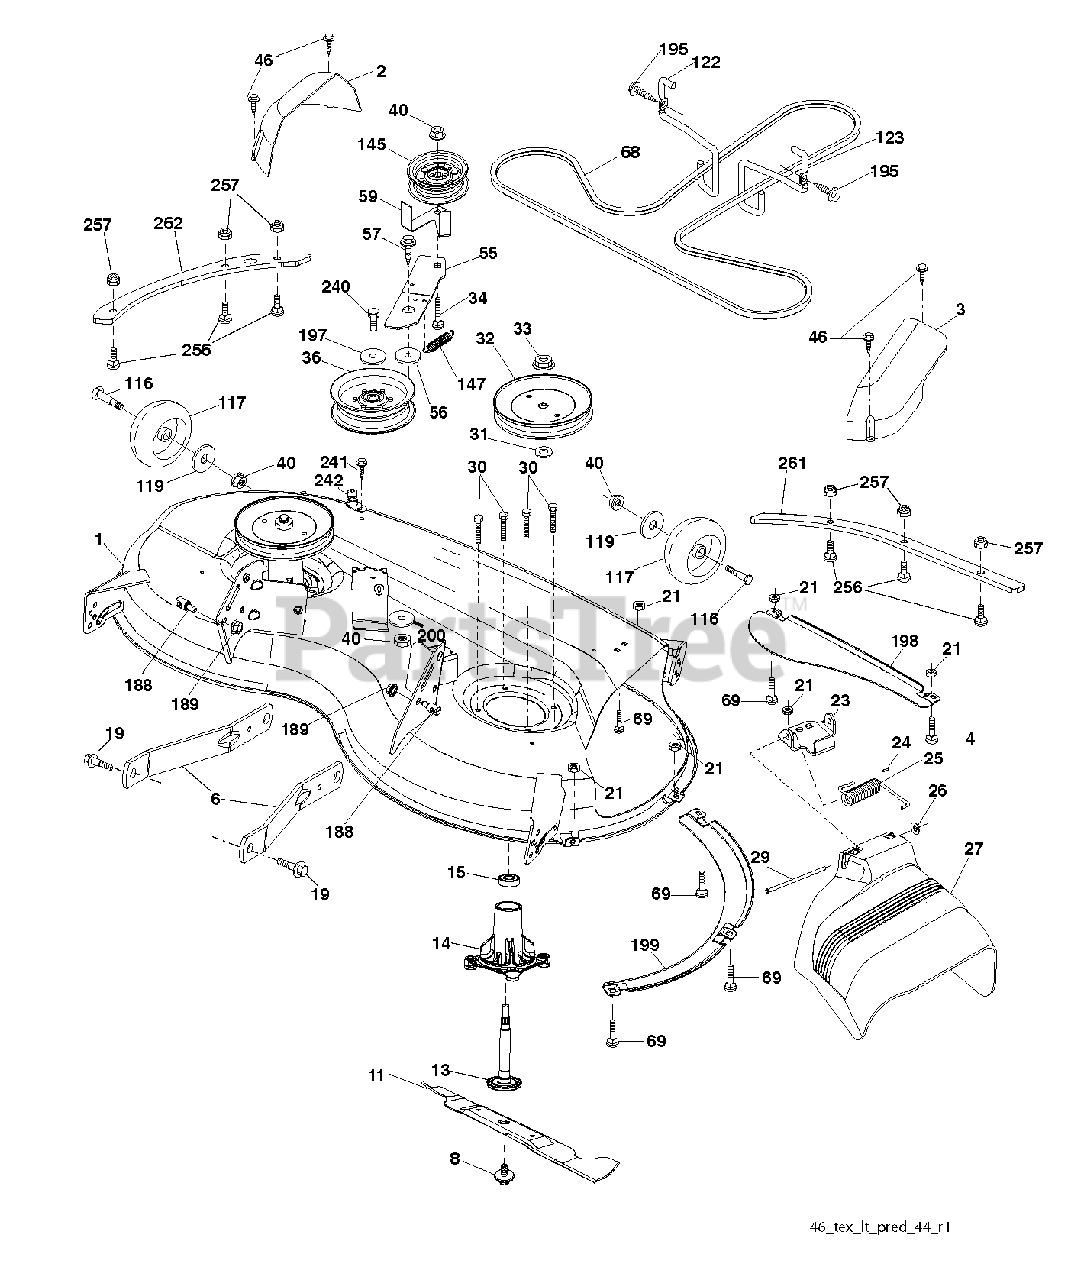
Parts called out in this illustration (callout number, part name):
1	DECK SVC 46"
2	COVER.MANDREL.RH.46"
3	COVER.MANDREL.LH.46"
4	BOLT
6	ARM.SUSPENSION.MOWER.R
8	BOLT.WASHER.ASM.7/16-2
11	BLADE.MOWER.46".HI.LIFT
13	SHAFT.ASM.MDRL.N/GREASE.38
14	HOUSING.MANDREL.4PT.
19	BOLT.SHOULDER
21	LOCKNUT
23	BRKT.DEFLECTOR.38"2005+
24	CAP-SLEEVE LT
25	SPRING.TORSION.DEFLECT
26	NUT PUSH M
27	SHIELD.DEFLECTOR.MOWER.46"BLAC
29	ROD.HINGE
30	SCREW, WASHER HEAD
31	WASHER.SPACER.MANDREL
32	PULLEY.MANDREL.5.438.PD
33	NUT.FLANGE.LOCK.TOP
34	BOLT.3/8-16X1.50
36	PULLEY.IDLER.2006
40	NUT LOCK FLG 3/8-16 UNC
46	SCREW.1/4-20X5/8
56	SPACER.RETAINER
57	SCREW 3/8-16X1
59	GUARD, BELT
68	V-BELT
69	BOLT
116	BOLT.SHOULDER.3/8-16X3-5/8.
117	WHEEL. GUAGE RALLY
119	WASHER
122	KEEPER BELT ENGINE LH
123	KEEPER BELT RH
145	PULLEY.IDLER.48"PRIMARY
147	SPRING.MOWER.DRIVE.ELECTRIC
188	STUD.FASTNER.W/ANTI-ROTATE
189	NUT LOCK HEX FLANGE 5/16-18
195	SCREW, 3/8-16X3/4
197	WASHER
198	BAFFLE CENTER FRONT
199	BAFFLE FRONT RH
200	WASHER.13/32 X 1 X 1/2.11GUARD
240	BOLT-HEX EAK
241	SCREW.TT.#10-32X.5.3/8.FLANGE
242	PORT.WASHOUT
256	SCREW.BUTTONHEAD.1/4-20X1
257	NUT T
261	PLATE.REINFOR.46.SIDEBOLT.X431
262	PLATE.REINFOR.46.SIDEBOLT.X431
